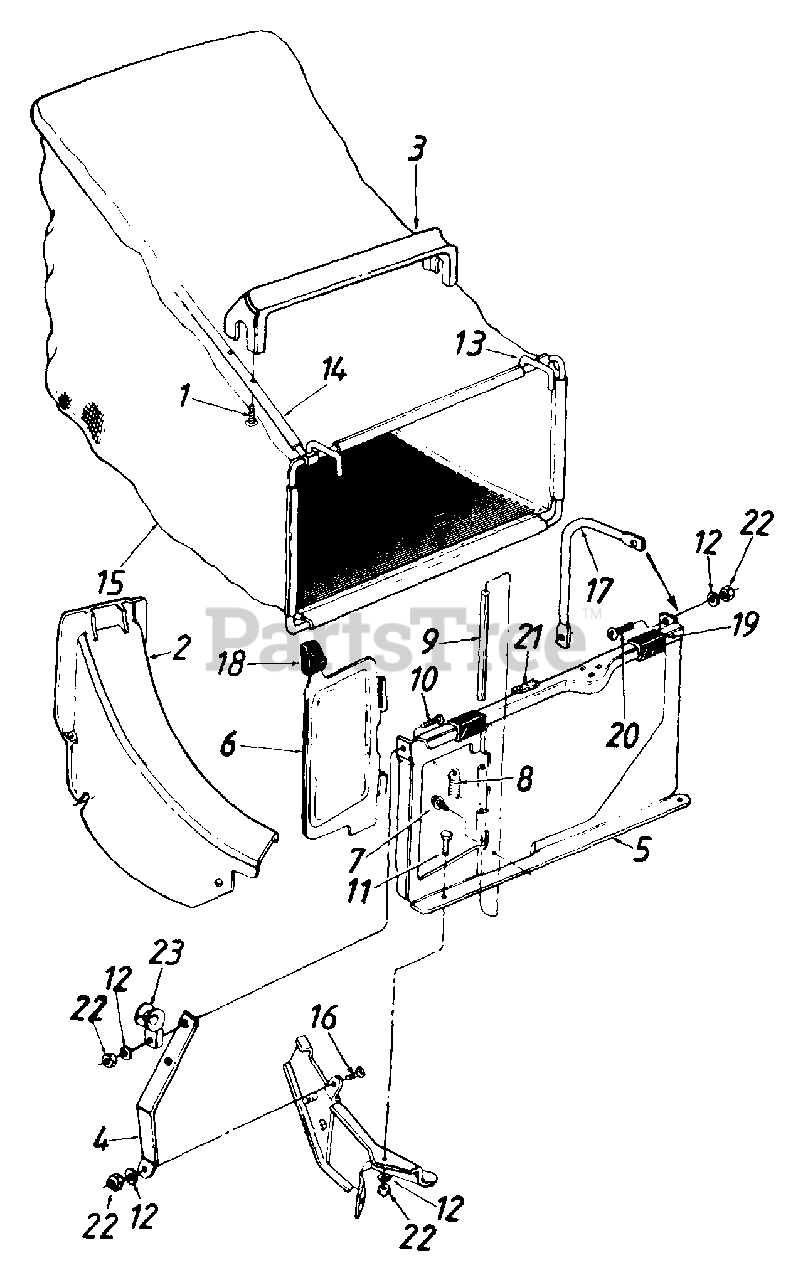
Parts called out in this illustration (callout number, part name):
1	Hex AB-Tap Scr. #12 x 1.25" Lg
2	Rear Discharge Chute Ass'y.
3	Bag Handle
4	Panel Support Brkt.
7	Hex B-Tap Scr. #10 x .38"
8	Torsion Spring
9	Pivot Pin
10	Truss Mach. Scr. 1/4-20 x 3/4" Lg.
11	Hex Bolt 1/4-20 x .50" Lg.
12	L-Wash. 1/4" I.D.
13	Front Grass Catcher Frame
14	Rear Grass Catcher Frame
15	21" Rear Discharge Grass Bag
16	Hex Bolt 1/4-20 x .62" Lg.
17	Catcher Panel Support Arm
18	Door Grip
19	Panel Clip
20	Truss Mach. Scr. 1/4-20 x .62" Lg.
21	Foam Strip
22	Hex Nut 1/4-20 Thd.
23	Rope Guide
